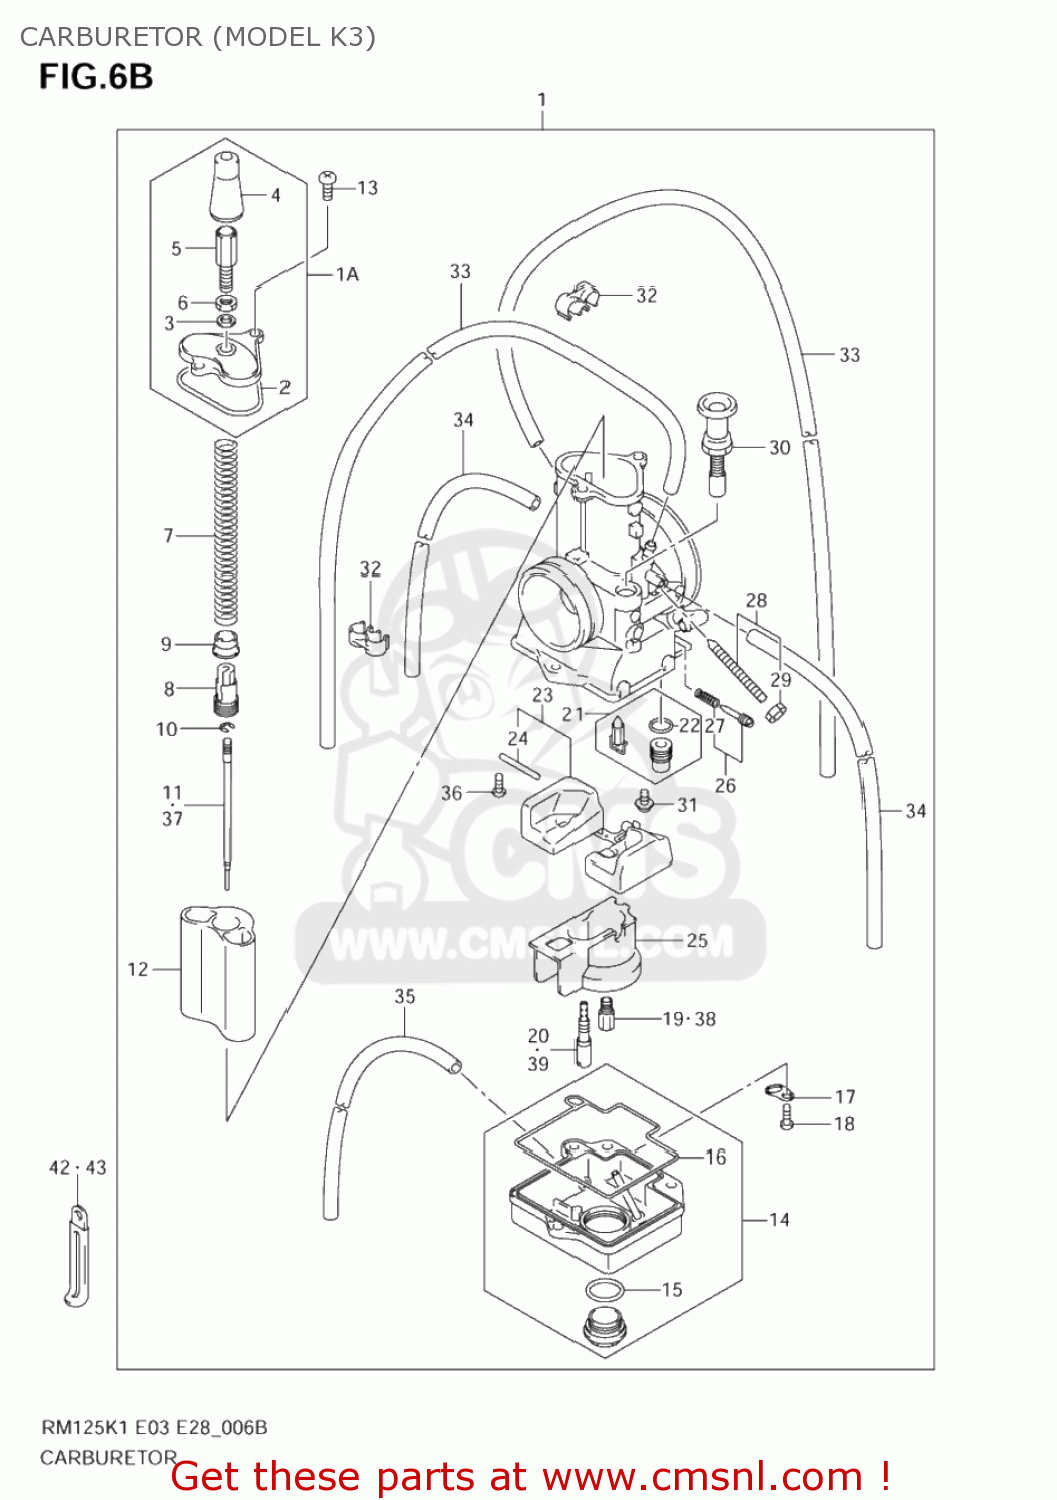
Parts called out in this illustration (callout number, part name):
1	CARBURETOR ASSY
1A	TOP CAP ASSY
2	PACKING (NAS)
3	WASHER,DRAIN PLUG
4	CAP,RUBBER
5	ADJUSTER,CABLE
6	NUT
7	SPRING
8	GUIDE HOLDER
9	RING
10	E RING,MULTIPLE JET NOZZLE
11	NEEDLE,JET(6BGY27-77)
12	VALVE,PISTON
13	SCREW
14	FLOAT BODY ASSY
15	O RING
16	O RING
17	PLATE,CARBURETOR
18	SCREW(5X14)
19	JET,MAIN(460)
20	JET,PILOT(40)
21	VALVE ASSY,NEEDLE
22	O RING,NEEDLE VALVE SEAT
23	FLOAT SET
24	PIN,FLOAT
25	HOLDER
26	ADJUSTER SET(AS)
27	SPRING
28	ADJUSTER SET (PV)
29	NUT
30	PLUNGER ASSY
31	SCREW
32	CLIP
33	HOSE(3.5X6.5X600)
34	HOSE(3.5X6.5X600)
35	HOSE(3X5X600)
36	SCREW
37	NEEDLE,JET(6BG
38	JET,MAIN(400)
39	JET,PILOT(25)
40	WASHER,JET NEEDLE CLIP
41	HOLDER,GUIDE
42	CLAMP(L:45)
43	CLAMP(L:65 T:0.8)
